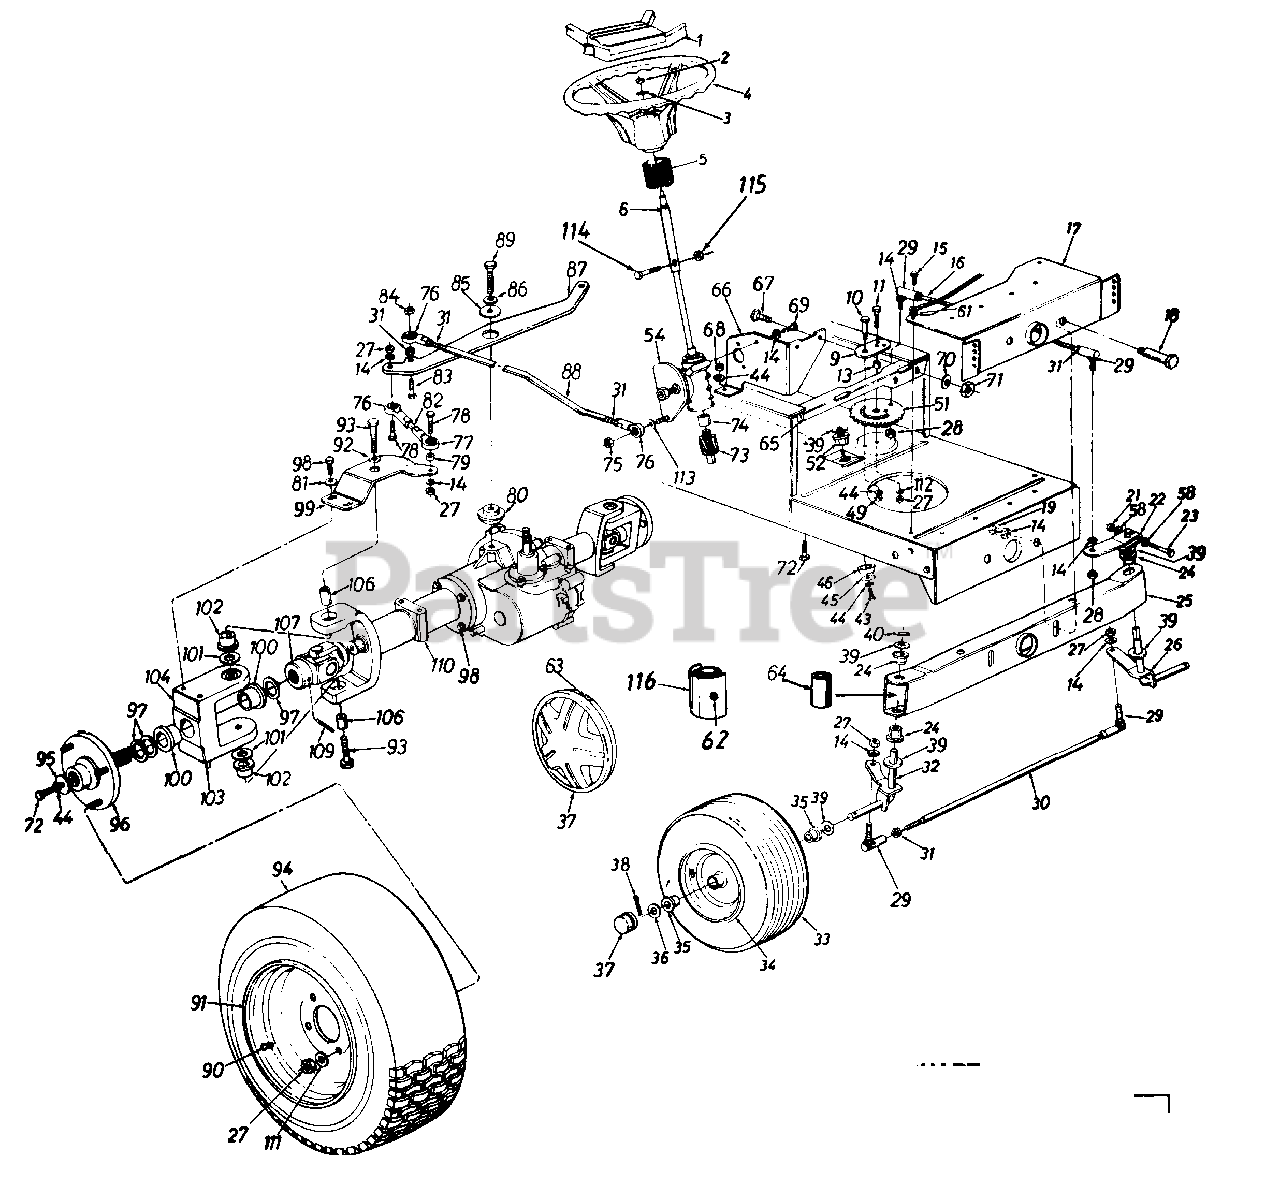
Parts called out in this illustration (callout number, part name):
1	Steering Wheel Insert
2	Hex L-Nut 5/16-24 Thd.
3	Belleville Wash. .345" I.D.
4	Steering Wheel (4 Spoke)
5	Steering Bellow
6	Upper Steering Shaft Ass'y.
9	Retainer Plate
10	Shoulder Bolt .437" Dia. x .35" Lg. 5/16-18 Thd.
11	Hex Bolt 3/8-24 x 1.0" Lg. (Grade 5)
13	Spacer .380" I.D. x .625" O.D. x .227"
14	L-Wash. 3/8" I.D.
15	Hex Wash. Hd. Self-Tap Scr.
16	Steering Drag Link
18	shoulder Bolt .498" Dia. x 2.04" Lg. 3/8-16 Thd.
21	Hex Cent. L-Nut 1/16-24 Thd.
22	Steering Arm Front Axle
23	Hex Bolt 5/16-24 x 2.00" Lg. (Grade 5)
24	Hex Flg. Brg. .634" I.D.
26	Front Axle Ass'y. - L.H.
27	Hex Nut 3/8-24 Thd.
28	Hex Jam Nut 3/8-24 Thd.
29	Ball Joint 3/8-24 Thd.
30	Tie Rod
31	Hex Jam Nut 3/8-24 Thd.
32	Front Axle Ass'y. - R.H.
35	Bearing - Plastic
36	Fl-Wash. .635" I.D. x 1.59" O.D.
37	Front Hub Cap
38	Cotter Pin 1/8" Dia. x 1.25" Lg.
39	Fl-Wash. .640" I.D. x .24" O.D.
40	Push Cap
43	Hex L-Bolt 5/16-18 x .62"
44	L-Wash. 5/16" I.D.
45	Fl-Wash. .33" I.D. x 1.25" O.D.
46	Spacer (Plastic)
49	Hex Nut 5/16-18 Thd.
51	Steering Gear Segment
52	Hex Flg. Brg. .634 I.D.
54	Steering Box Ass'y, Comp.
58	Wave Wash. .32" I.D. x .62"
61	Ext. Lash. 5/16" I.D.
62	Grease Fitting
63	Spring Clip
64	Spacer
65	Horizontal Cross Bracket
66	Vertical Mounting Bracket
67	Hex Bolt 1/4-28 x .75" Lg.
68	Hex Nut 5/16-24 Thd.
69	Hex Bolt 3/8-16 x 1.0" Lg.
70	Bell-Wash. .265" I.D. x .75"
71	Hex Nut 1/4-28 Thd.
72	Hex Bolt 5/16-24 x .75" Lg.
73	Pinion Shaft
74	Steering Shaft Splined Coupler
75	Hex L-Nut 3/8-24 Thd.
76	Rod End 3/8-24 Thd. - R.H.
77	Rod End 3/8-24 Thd. - L.H.
78	Hex Bolt 3/8-24 x 1.5" Lg. (Gr. 5)
79	Spacer .38" I.D. x .625"
80	Shld. Spacer .51" I.D.
81	Bell-Wash. .38" I.D. x .88"
82	Tie Rod
83	Hex Bolt 3/8-24 x 1.25" Lg.
84	Hex Patch L-Nut 3/8-24 Thd.
85	Fl-Wash. .531" I.D. x 1.75"
86	Bell-Wash. .505" I.D. x 1.0"
89	Hex Bolt 1/2-13 x 1.5" Lg. (Gr. 5)
90	Air Valve
93	Hex Bolt 1/2-20 x 1.75" Lg. (Gr. 5)
95	Fl-Wash. .33" I.D. x 1.25"
96	Wheel Flange Ass'y.
97	Fl-Wash. 1.0" x 1.56"
98	Hex Bolt 3/8-24 x 1.25" Lg.
101	fl-Wash. .76" I.D. x 1.5"
102	Flange Brg. 3/4" I.D.
103	Grease Fitting
104	Wheel Brg. Housing
106	Pivot Sleeve
107	U-Joint
109	Grooved Roll Pin 1.0" Lg.
110	Axle Horn Ass'y.
111	Bell-Wash. .38" I.D. x .88"
112	Bell-Wash. .39" I.D. x 1.38"
113	Fl-Wash. .385" I.D. x .62"
114	Hex Bolt 1/4-20 x 1.31" Lg.
115	Hex Ins. L-Nut 1/4-20 Thd.
116	Pivot Bar End Cap
